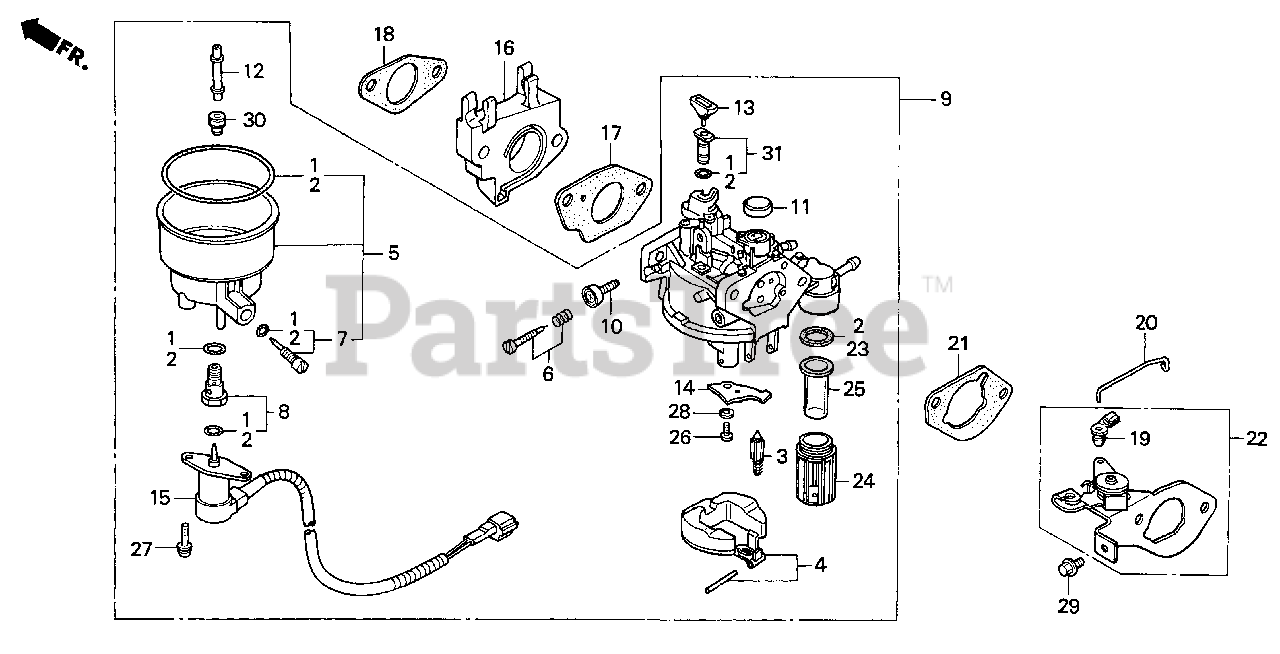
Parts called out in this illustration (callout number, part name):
1	GASKET SET
3	VALVE SET, FLOAT
5	CHAMBER SET, FLOAT
7	SCREW SET, DRAIN
9	CARBURETOR ASSY. (BE31A C)
10	SCREW, THROTTLE STOP
11	CAP, CHOKE DUST
12	NOZZLE, MAIN
15	VALVE ASSY., SOLENOID
16	INSULATOR, CARBURETOR
17	GASKET, CARBURETOR
18	GASKET, INSULATOR
19	JOINT, ROD
20	ROD, CHOKE
21	GASKET, AIR CLEANER
22	CONTROL ASSY., CHOKE (REMOTE)
24	HOLDER, CUP
25	CUP, FUEL STRAINER
27	SCREW-WASHER (5X12)
29	BOLT, FLANGE (6X8)
30	JET, MAIN (#100)
30	JET, MAIN (#102)
30	JET, MAIN (#105)
31	JET SET, PILOT (#40)
